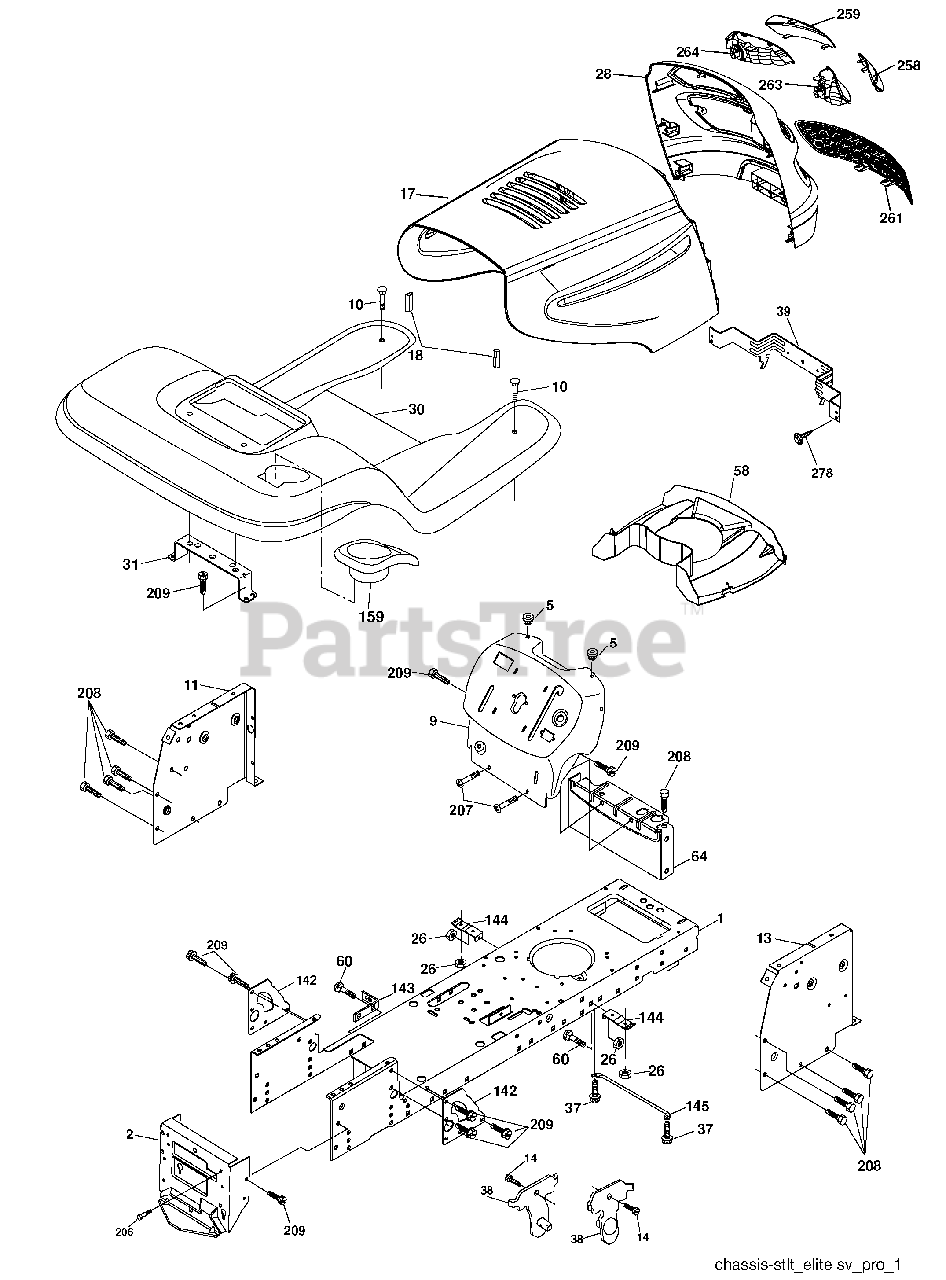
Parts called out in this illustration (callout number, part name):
1	Chassis
2	Drawbar
5	Bumper Hood/Dash
9	Dash P/L
10	Bolt Carriage 3/8-16 x 1
11	Panel Dash Lh
14	Screw THDROL 3/8-16 x 1/2
17	Hood
18	Bumper Hood
26	Nut Lock Hex W/Ins 3/8-16 unc
28	Grille/Lens Asm
31	Bracket Fender
37	Screw Thdrol 6/16-18 x 1/2 TYT
38	Bracket Asm Pivot Mower Rear
39	Bracket Pivot
58	Duct Air
60	Bolt RDHD SQNK 3/8-16 unc x 1
64	Dash Lower STLT
142	Plate Reinforcement STLT
143	Bracket Swaybar Chassis
144	Bracket Footrest
145	Rod Pivot Chassis/Hood
159	Cupholder
206	Bolt Shoulder 5/16-18
207	Screw Thdrol 5/16-18 x 1/2
208	Screw Thdrol 3/8-16 x 1/2
209	Screw Hexwsh Thdr 3/8-16 x 3/4
258	Lens Grille Pro RH
259	Lens Grille Pro LH
263	Bezel Grille RH
264	Bezel Grille LH
278	Screw 10 x 3/4 Single Lead
278	Plug BTN BlK
278	Plug Domed Plastic
